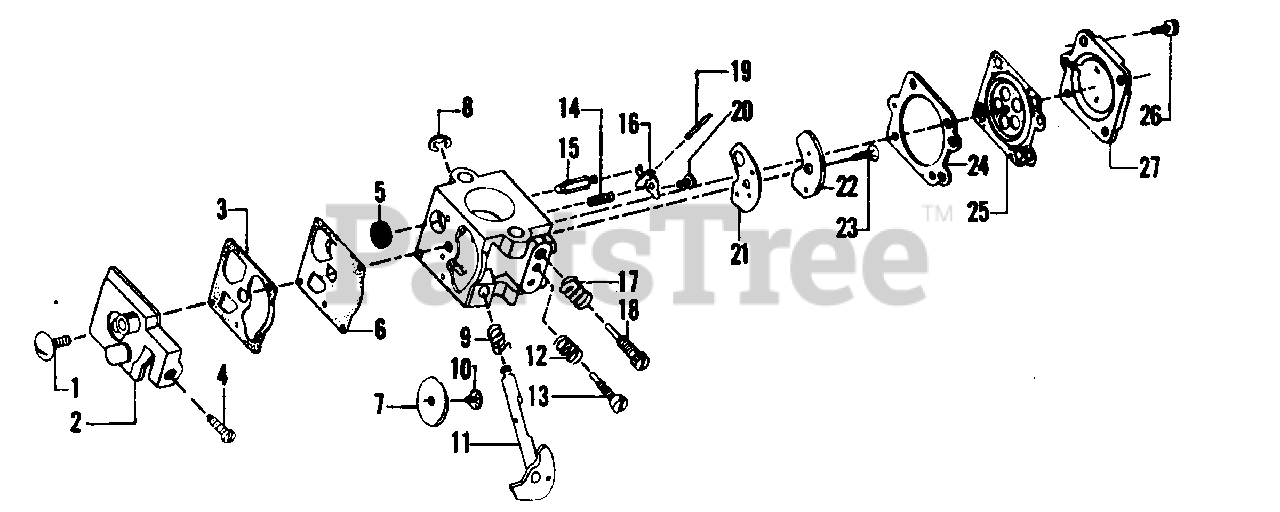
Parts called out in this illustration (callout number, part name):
1	Screw - Pump Cover
2	Pump Cover Ass'y (Incl. #4)
3	Gasket -Pump
4	Screw - Idle Adjustment
5	Screen - Inlet
6	Diaphragm - Pump
7	Valve - Throttle
8	Clip - Throttle Shaft
9	Spring - Throttle Return
10	Screw - Throttle Valve
11	Shaft Assembly - Throttle
12	Spring - Idle Needle
13	Needle - Idle
14	Spring - Metering Lever
15	Valve - Inlet Needle
16	Lever - Metering
17	Spring - Hi Speed Needle
18	Needle - Hi Speed
19	Pin - Metering Lever
20	Screw - Metering Lever Pin
21	Gasket - Circuit Plate
22	Plate - Circuit
23	Screw - Circuit Plate
24	Gasket - Metering Diaphragm
25	Diaphragm Assembly-Metering
26	Screw Assembly - Metering Cover & Throttle Shaft Clip
27	Cover - Metering Diaphragm
28	Kit - Carb. Kwik Repair
29	Kit - Carb. Gasket / Diaphragm
